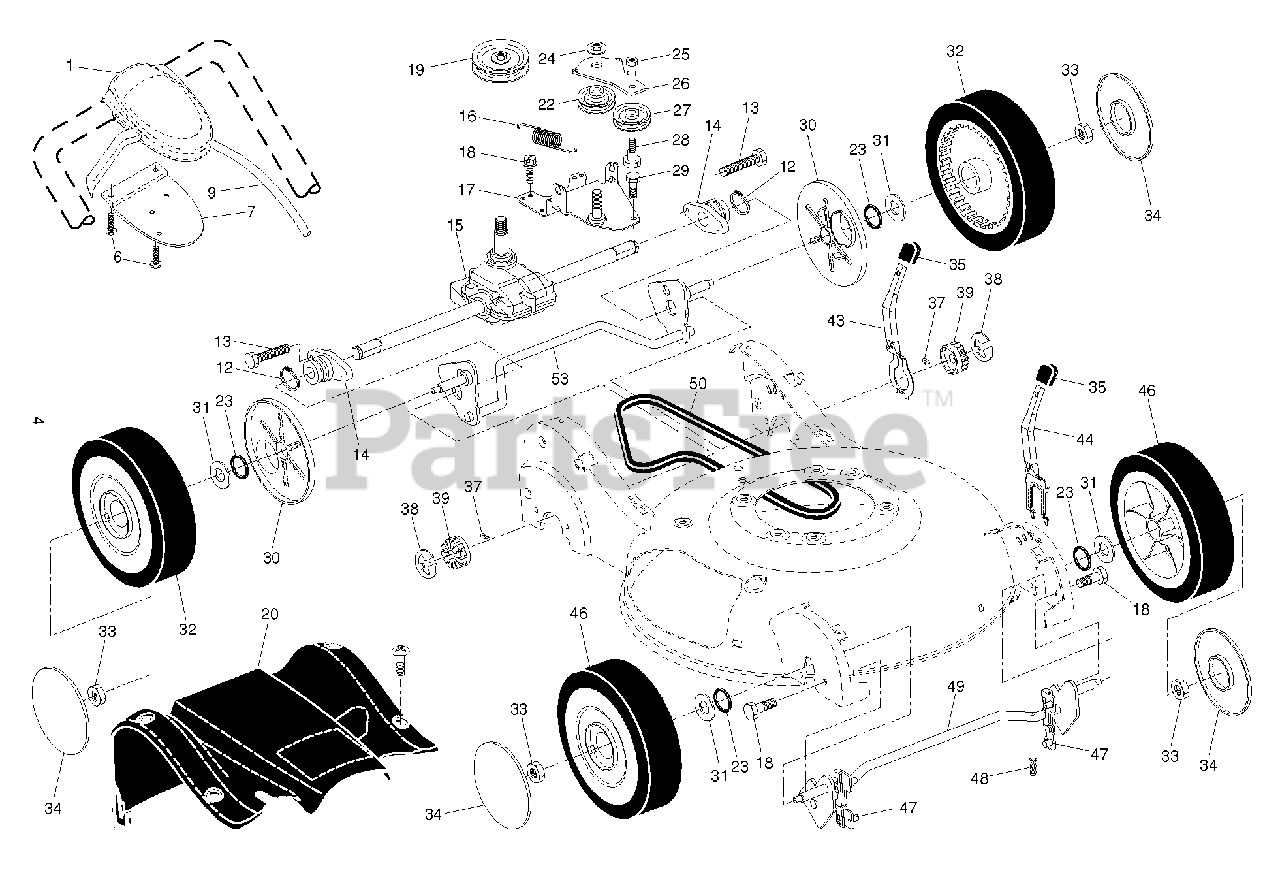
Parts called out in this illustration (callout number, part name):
1	Drive Control Assembly, Complete
6	SCREW, PHILLIPS HEAD 10 X 5/8
7	BRACKET.DRIVE.CONTROL.MOUNT.BL
9	ASM.CABLE.
12	RETAINING RING (2 2)(3 2)
13	SCREW.1/4-20X21/4.HEX.
14	BEARING / AXLE SUPPORT
15	TRANSMISSION.21.HV.RWGD.AW/EZ
17	BRACKET, GEAR CASE / DRIVE
19	RP PULLEY.DRIVE.EZ/VAR.SCREWON
20	COVER.DR.ASM.408006X418.CE
22	PULLEY.IDLER.V-BELT
23	O-RING..070X.487.NEOPRENE
24	NUT.HEX.FLANGE.3/8-16.LOCKNUT
25	NUT.CENTERLOCK.5/16-
26	ARM.IDLER.BZP
27	IDLER PULLEY
28	SHOULDER BOLT
29	SCREW 14-20 X 5/8
30	DUST COVER, WHEEL
32	WHEEL.9X2.25.LP.TIGER.BLACK
33	NUT.HEX.FLANGE.3/8-16.LO(3 2)
34	HUBCAP.WHEEL.5.SPOKE.SILVER
35	KNOB.SELECTOR.SPRING.BLACK(3 2
37	PAWL, DRIVE
38	E-RING 7/16 RE
39	PINION.14.TEETH.FGD
43	LEVER, SELECTOR, HEIGHT, REAR
44	LEVER, SELECTOR, HEIGHT, FRONT
46	WHEEL.9X2.25.LP.TIGER.BLK
47	BUSHING.FRONT.TORQUE.SHAFT
48	SPRING RETAINER
49	SHAFT FRONT
50	BELT, DRIVE
53	SHAFT.ASM.REAR.TORQUE.HV.BZP
